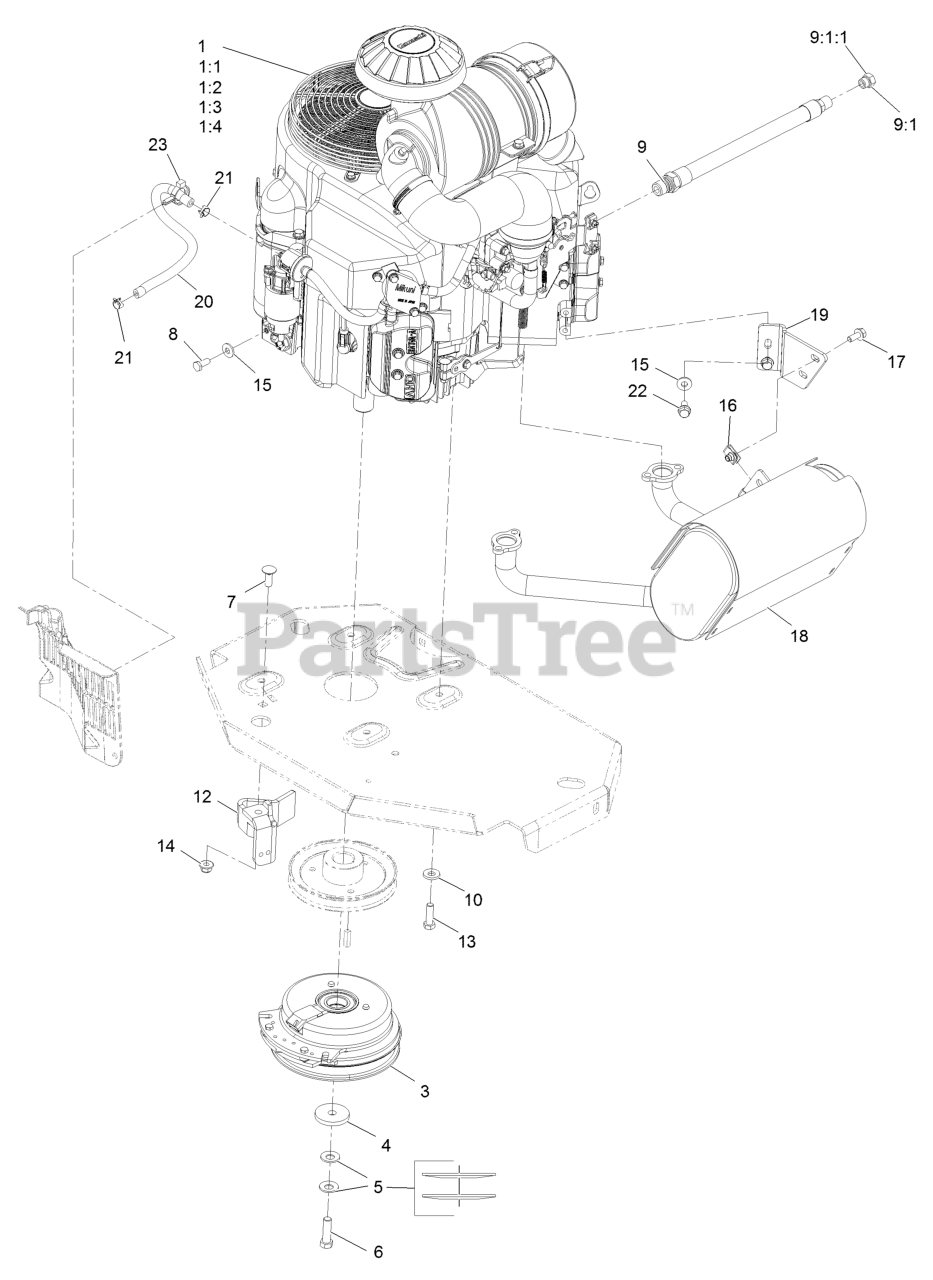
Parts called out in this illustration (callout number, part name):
3	Clutch Kit
4	Washer-Clutch
5	Washer-Spring Disc 7/16
6	Screw-HH 7/16-20 X 1 1/2 W/Loctite
7	Bolt-Carriage 3/8-16 X 1
8	Screw-HH M8-1.25 X 20Mm
9	Asm-Hose Oil Drain W/Plug
9:1	Plug-W/O-Ring
9:1:1	O-Ring
10	Washer-Spring Disc 3/8
12	Clutch-Anchor
13	Screw-HH 3/8-16 X 1 1/4
14	Nut-Nyloc 3/8-16 Flg
15	Washer-Spring Disc 5/16
17	Screw-HH Flg 5/16-18 X 3/4
18	Muffler
19	Bracket-Muffler
20	Hose-Fuel Line 15"
21	Clamp-Hose
22	Screw-HHF
23	Clamp-Hose
